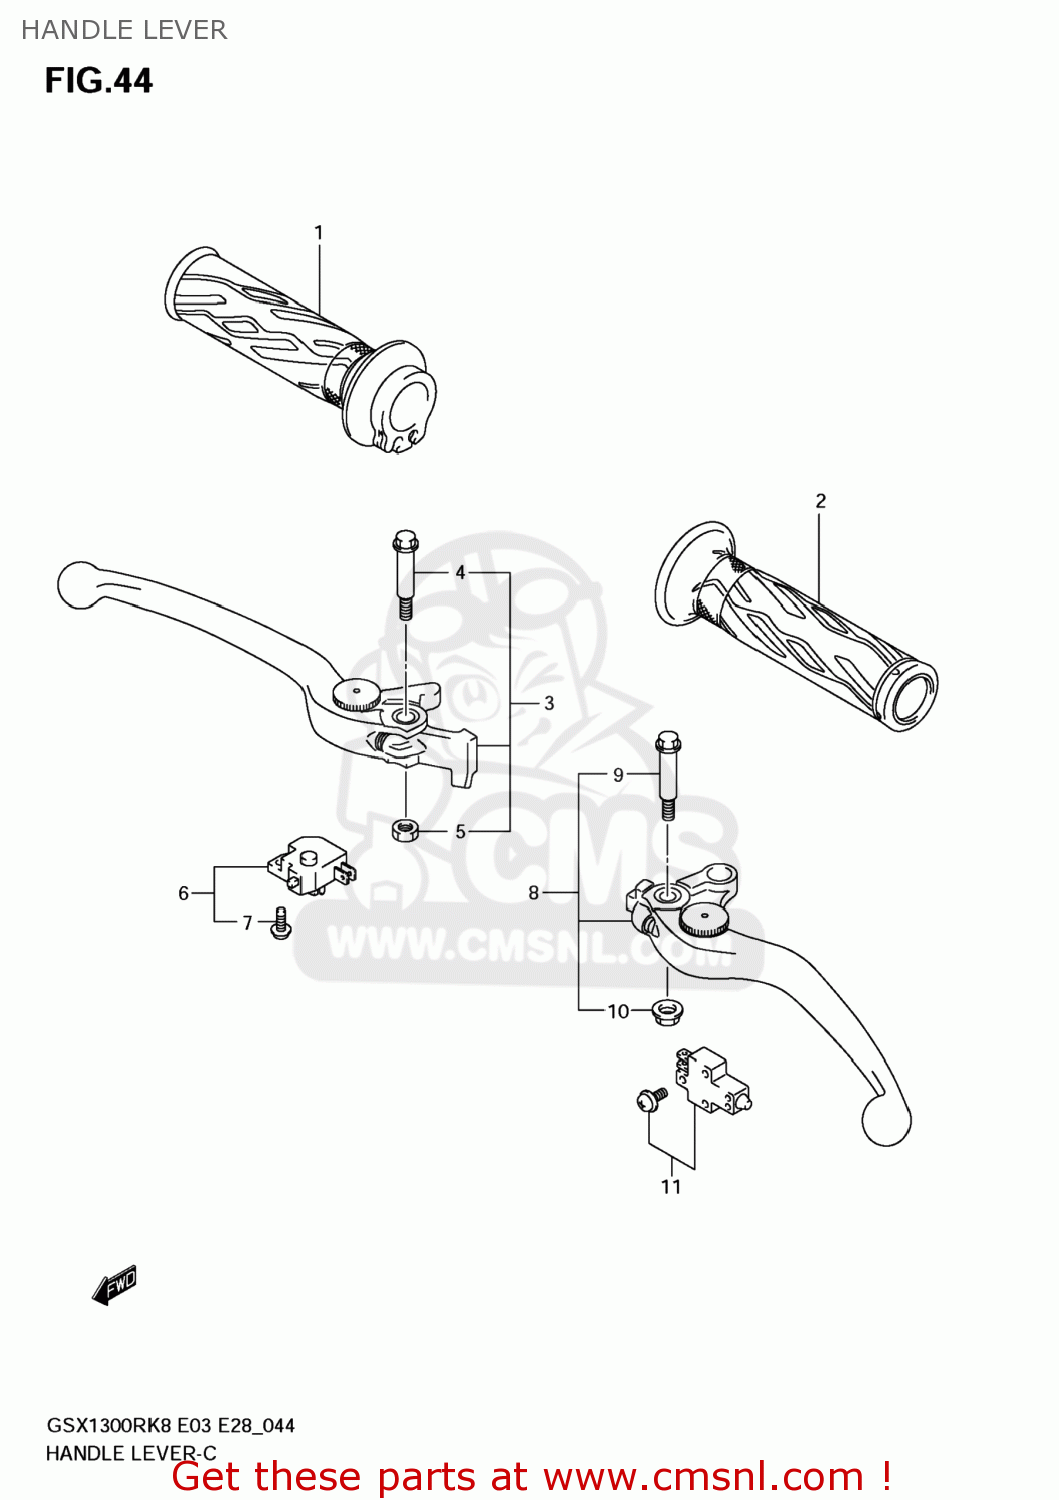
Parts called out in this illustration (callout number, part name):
1	GRIP,THROTTLE
2	GRIP,L
3	LEVER ASSY,BRA
4	BOLT,PIVOT
5	NUT
6	SWITCH ASSY,ST
7	SCREW
8	LEVER ASSY,CLU
9	BOLT,PIVOT
10	NUT
11	SWITCH ASSY,CLUTCH
